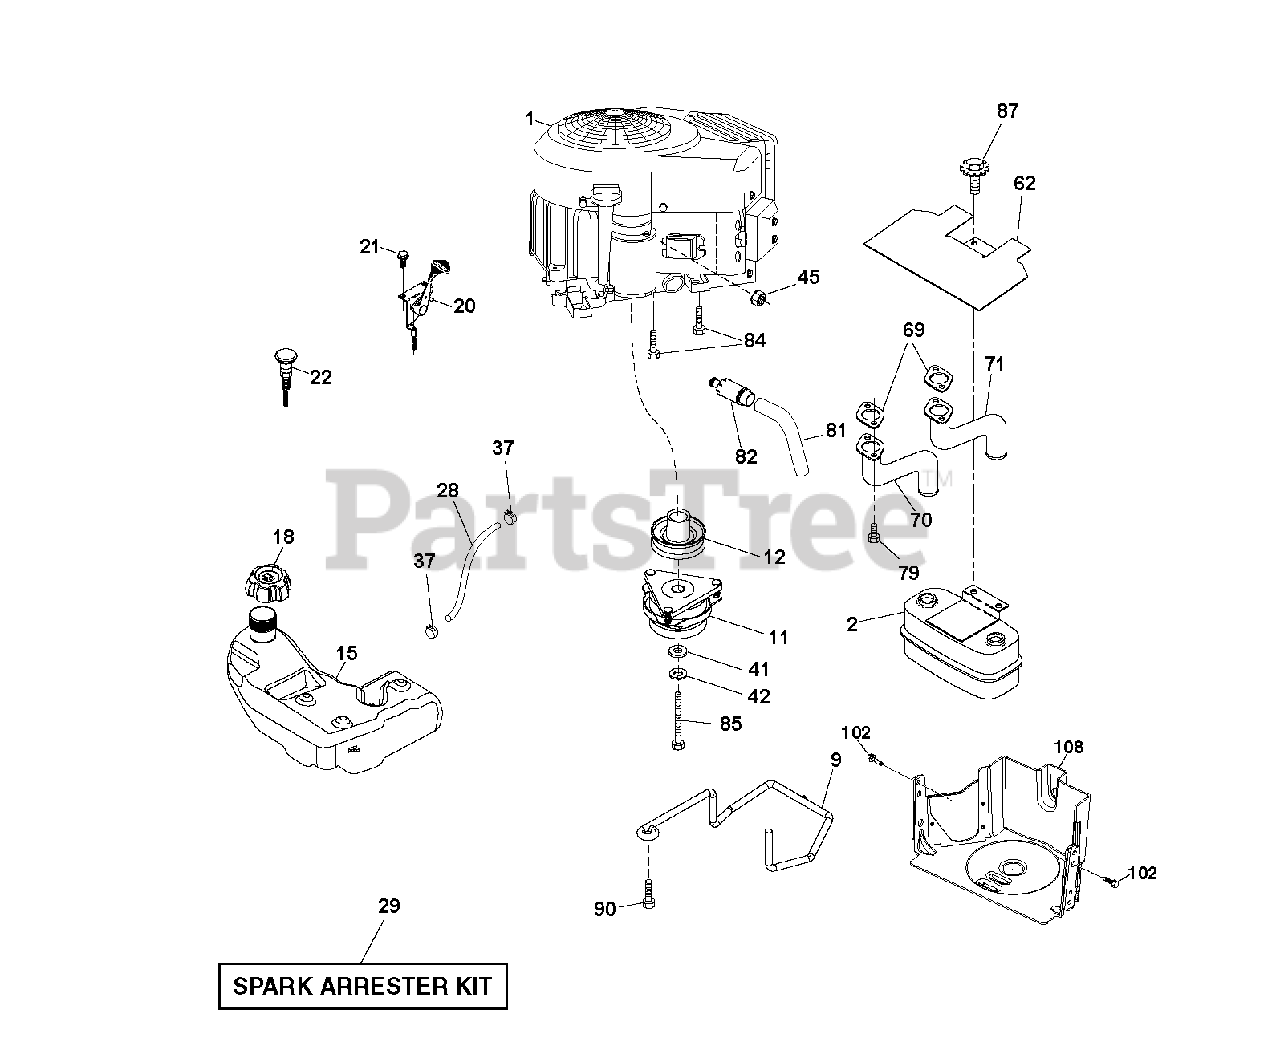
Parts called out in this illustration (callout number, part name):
2	MUFFLER.TWIN.CYL.LOW.TONE
9	KEEPER.BELT.ENGINE.4.2
11	CLUTCH ELECTRIC
12	PULLEY ENGINE
15	TANK.FUEL.4GAL
18	CAP.ASM.FUEL.TANK.3"BLACK
20	THROTTLE CABLE
21	SCREW.#10 X 0.750.BOS THREAD
22	CONTROL CHOKE
28	LINE.FUEL.20
29	ARRESTER SPARK (OPTIONAL)
37	HOSE CLAMP
42	LOCKWASHER
45	NUT
62	RP SHIELD HEAT MUFFLER
69	GASKET.MUFFLER
70	TUBE MANIFOLD LH
71	EXHAUST TUBE RH
79	SCREW.SOCKET.HEAD.5/16-18
81	TUBE, DRAIN OIL ASM.
82	VALUE.OIL.DRAIN
84	SCREW.3/8-16
85	BOLT HEX 7/16-20 X 3.75 GR. 5
87	BOLT, 5/16-18 X 1 3/4
90	SCREW 3/8-16X1
102	SCREW
